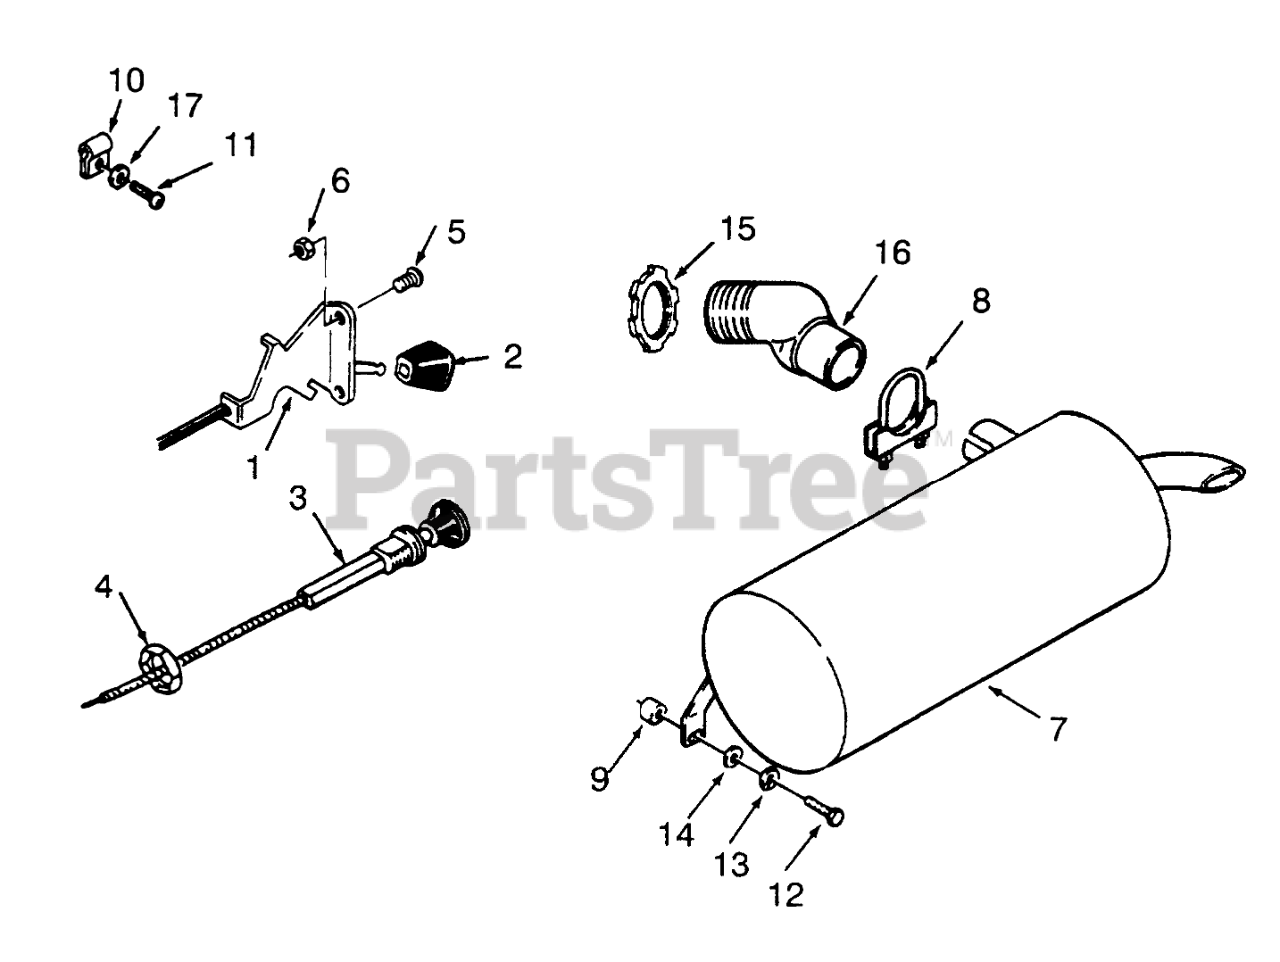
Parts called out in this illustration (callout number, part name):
1	CONTROL-THROTTLE
2	KNOB-CONTROL
3	CONTROL CHOKE
4	NUT-HEX PALNUT
5	Screw
6	Nut
7	Muffler
8	CLAMP-1 1/2
9	SPACER
11	Screw
12	SCREW-HH
13	WASHER-LOCK
14	WASHER-FLAT
15	Nut-Lock
16	Elbow
17	Washer
